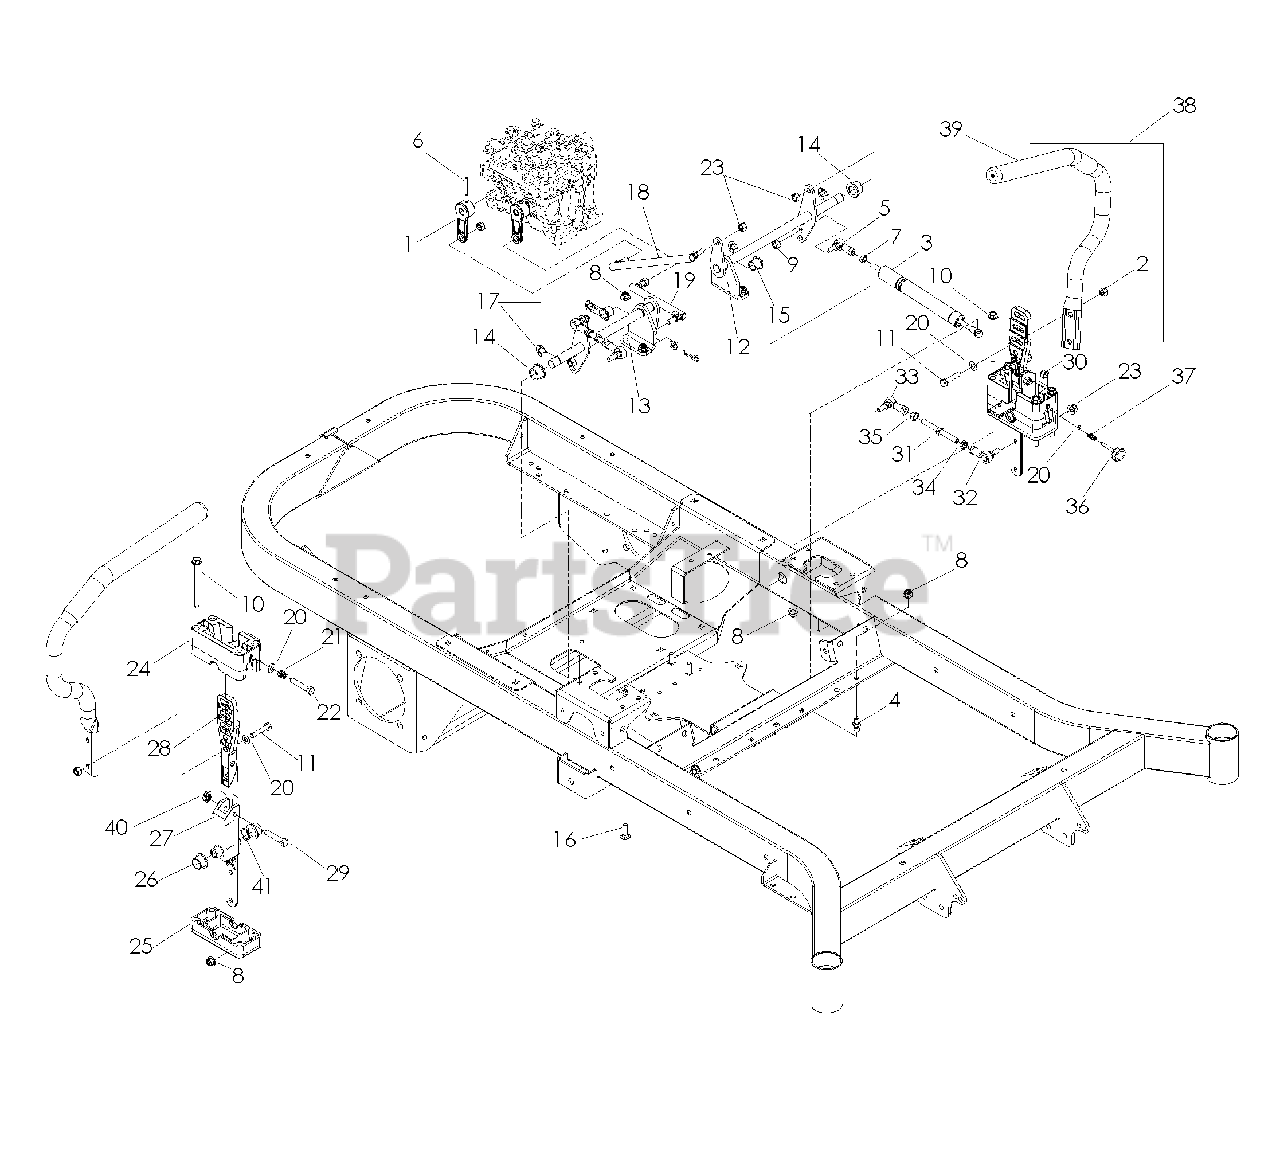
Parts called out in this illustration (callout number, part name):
1	ARM, PUMP
2	NUT 5/16-18 HEX NYLOC
3	DAMPENER W/SPRING
4	STUD, 10MM BALL
6	PIN, SPIRAL, 5/32 X 1 1/2
7	NUT M8 x 1.25 STD HEX
8	NUT 5/16-18 FLANGE NYLOC
9	NUT M8 NYLOC
10	HHFS 5/16-18 x 3 3/4
11	HCS 5/16-18 x 1 1/2
12	CONTROL WLDMT, LT
13	CONTROL WLDMT, RT
14	BUSHING, FLANGED, 5/8
15	BUSHING, CLIP, 5/8
16	RHSNB 5/16-18 x 1
18	LINK, MOTION, LT
19	LINK, MOTION, RT
20	WASHER 5/16 SAE FLAT
21	SPRING, TANK MOUNT
22	HCS 5/16-18 x 1 3/4 TPBLT
23	NUT 5/16-24 CNTRLK
24	BLOCK, UPPER
25	BLOCK, LOWER
26	BEARING, FLANGE
27	PIVOT SECTION, DR CNTRL
28	MOUNT, DR CNTRL HANDLE
29	HCS 5/16-18 x 1 3/4
30	NUT 5/16-18 HEX
31	JACK SCREW
32	SPHERICAL ROD END LH
33	SPHERICAL ROD END RH
34	NUT 5/16-24 HEX JAM LH
35	NUT 5/16-24 HEX
38	LEVER, DRIVE W/GRIP RT
38	LEVER, DRIVE W/GRIP LT
39	GRIP, DRIVER LEVER
40	NUT, 5/16-18, FLANGE, NYLOC
41	WASHER, .825, WAVE
